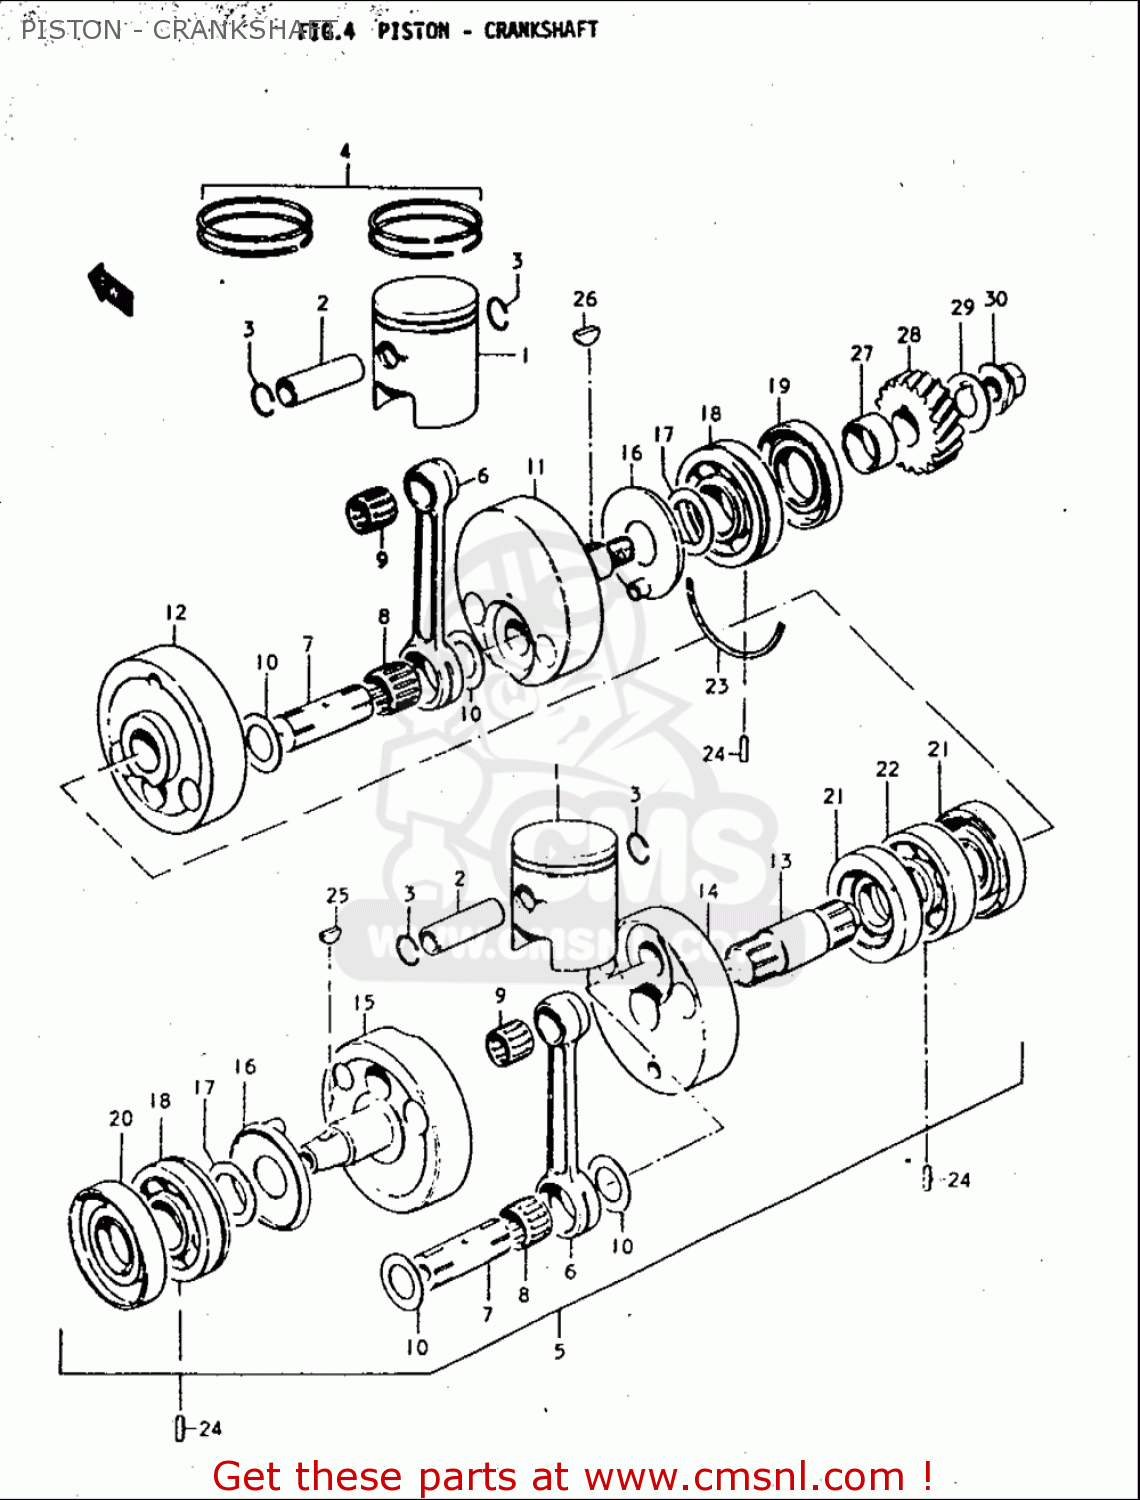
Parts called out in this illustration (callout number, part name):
2	PIN,PISTON
3	RING,SNAP 16MM
4	RING SET,PISTON
8	BEARING(20X26X16.7)
9	BEARING(16X21X19.6)
10	WASHER (20X34X1)
17	SHIM(25X40X1)
18	BEARING(25X65X17)
19	SEAL,OIL
20	SEAL,OIL(25X65X12)
21	SEAL,OIL
25	KEY
26	KEY
29	WASHER
